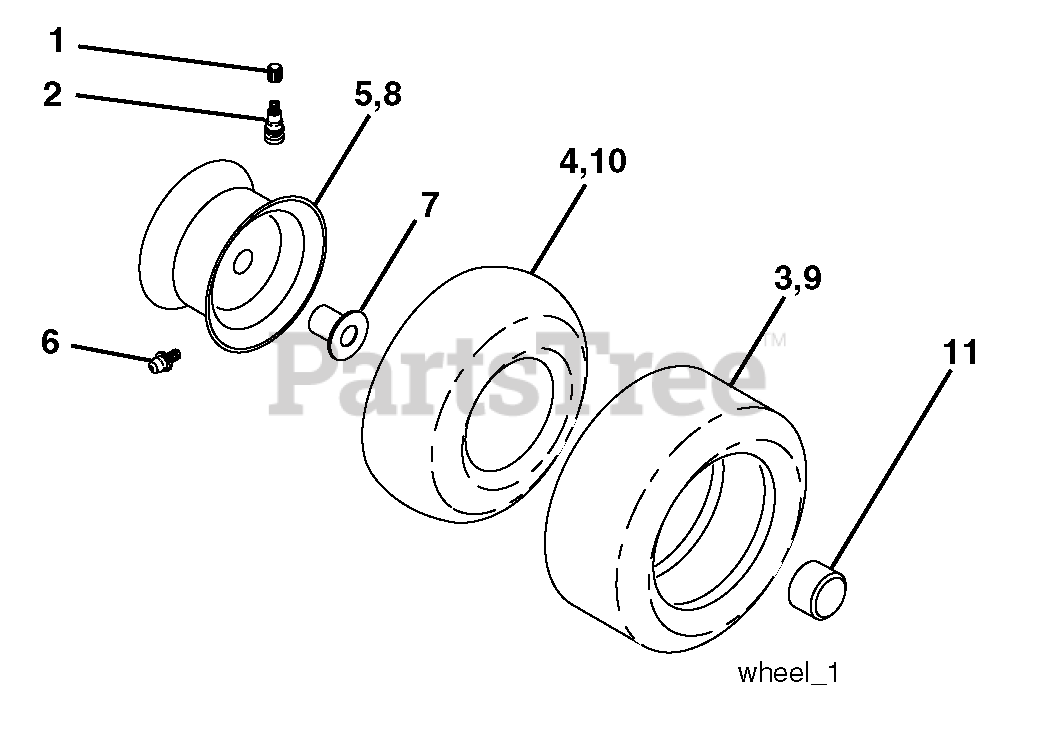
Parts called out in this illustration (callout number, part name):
1	Cap Valve Tire
2	Stem Valve
3	Tire F T 15 x 6 0 - 6
4	Tube Front
5	Rim Asm 6" Front
6	Fitting Grease (Front Wheel Only)
7	Bearing Flange (Front Wheel Only)
8	Rim Asm 8" Rear
9	Tire R T 18 x 9.5-8 Turf Saver
9	Tire R T 18 x 9.5-8 Turf Saver LT
10	Tube Rear
11	Cap Axle
11	Sealant, Tire ( 10 oz. Tube)
